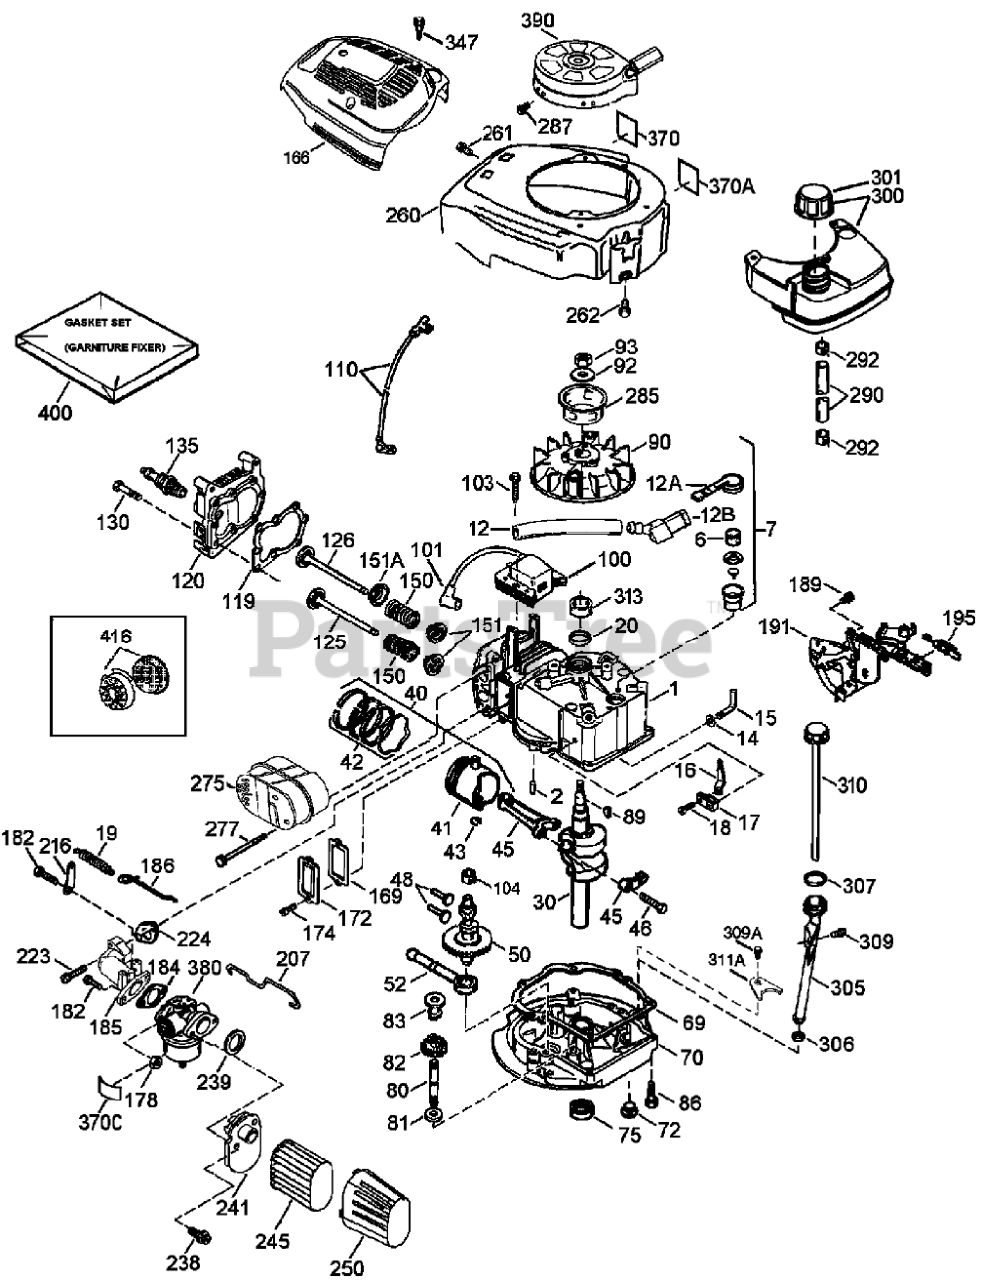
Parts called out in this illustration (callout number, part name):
347	Screw (10-32 x 27/32)
370	Decal-Warning
370A	Decal-Lubrication
370C	Decal-Primer
380	(Incl. Ref. #184 of Engine Parts List)
390	Rewind Starter ASM
400	Gasket Set (Incl. Items Marked PK in Notes)
416	Spark Arrestor Kit
